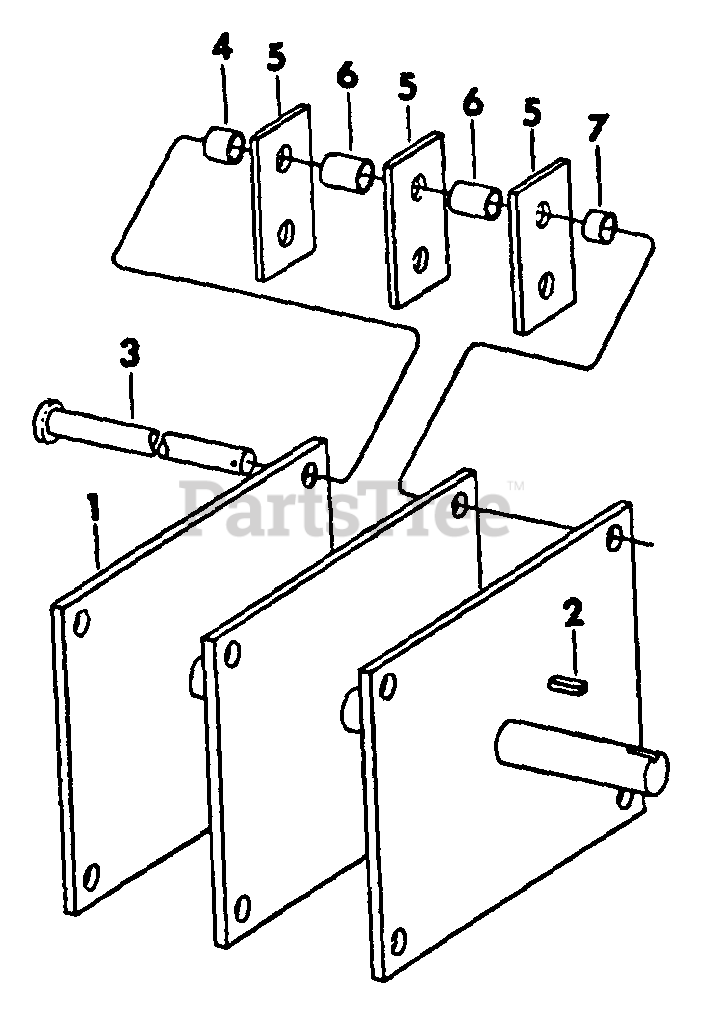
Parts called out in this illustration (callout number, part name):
1	ROTOR
2	KEY. 1/4 X 1 SQ PARALLEL
3	ROD, HAMMER
4	SPACER
7	SPACER
103407	PIN, 3/16 X 1 COTTER
